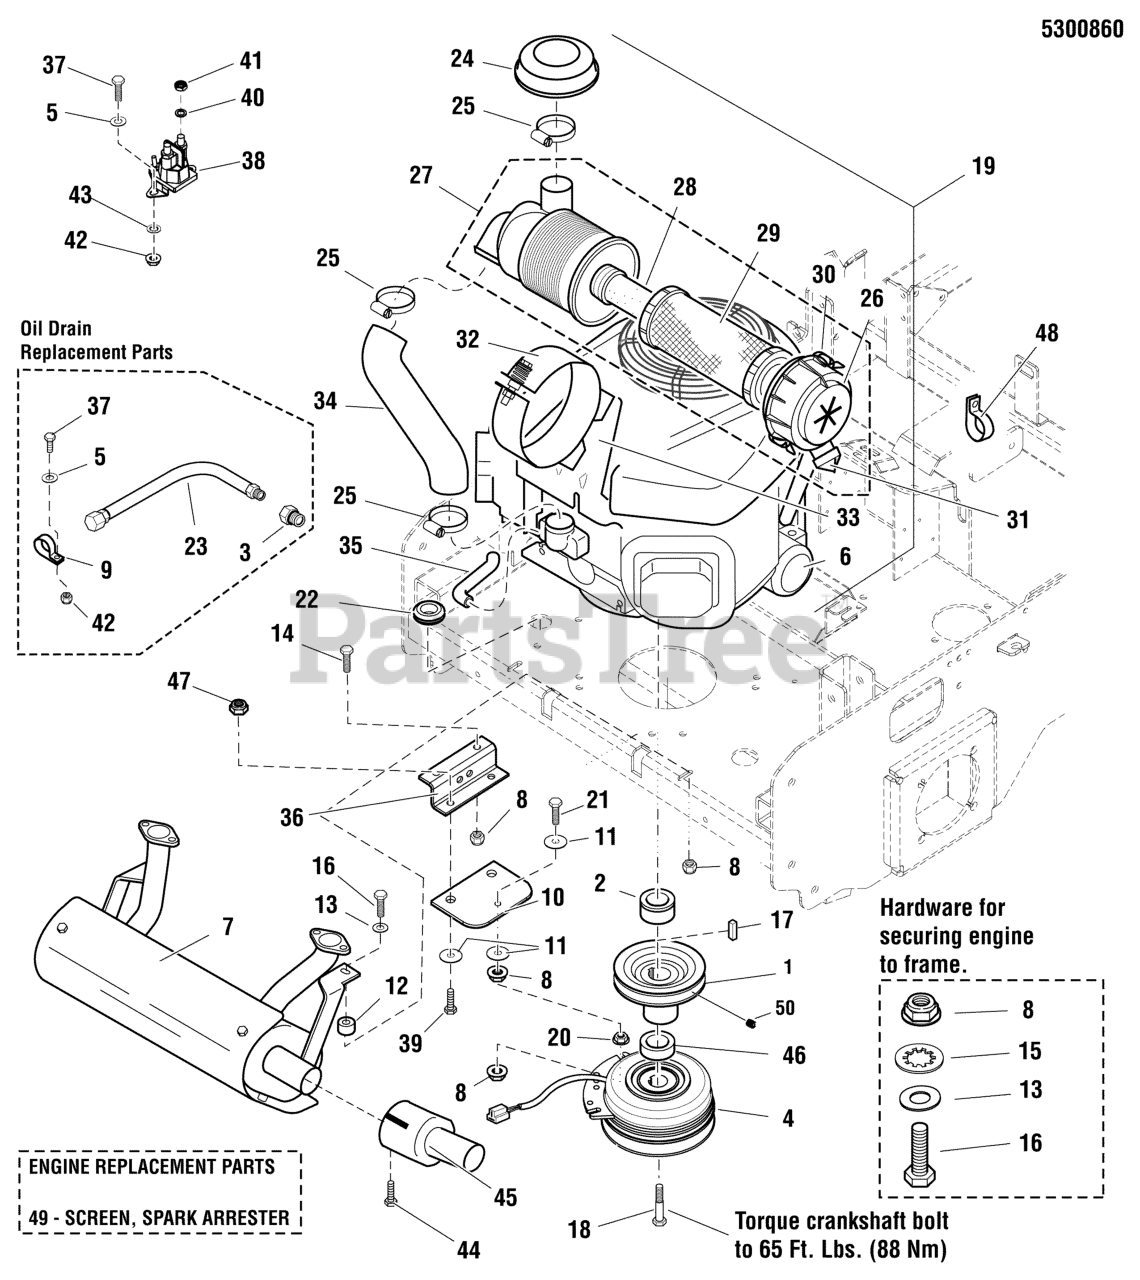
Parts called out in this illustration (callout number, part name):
1	PULLEY, 5.15 OD X 1-1/8 BORE B-SECT
2	SPACER, 1.13 X 1.75 X 1.03, CZ
3	ADAPTER, Oil Drain
4	CLUTCH WARNER 200 FT-LB 1.13 X 6.323
5	WASHER, 1/4 SAE
6	FILTER,OIL,KAWA FX751,801,851,921,100
7	MUFFLER, 21HP-25HP KAWASAKI ENGINES
8	NUT, 5/16-18 HEX NYLOCK FLANGE NUT
9	CLAMP, VINYL INSULATED, 1.00
10	CLUTCH ANCHOR PAD
11	WASHER, .34 X 1.25 X 10 GA
12	SPACER, .39 X 1.00 X .80, CZ
13	WASHER, 5/16" SAE
14	BOLT, 5/16-18 X 1" GRD5 YZ
15	WASHER, 5/16" Internal Tooth Lock
16	BOLT, 5/16-18 X 1-3/4" GD5 YZ
17	KEY, 1/4 SQ X 1
18	BOLT, CRANKSHAFT, 7/16" X 2-1/2"
20	NUT, 5/16-18 HEX SERRATED FLANGE (LARGE)
21	BOLT, 5/16-18 X 2-1/4 TFL, GD5 YZ
22	GROMMET, 7/8"
23	HOSE, OIL DRAIN
24	RAIN CAP, AIR FILTER, 22,24&26HP, KAWASAKI (SV)
25	CLAMP, HOSE
26	CAP END, FILTER CASE
27	AIR FILTER ASSEMBLY, Complete
28	AIR FILTER, ELEMENT, SECONDARY
29	AIR FILTER, ELEMENT, PRIMARY
30	CLAMP, Cap
31	RUBBER, Dust Valve (SV)
32	CASE, BRACKET, COMPLETE
33	BRACKET PLATE
34	AIR INLET TUBE
35	BREATHER TUBE
36	ANCHOR, CLUTCH - BLK
37	BOLT, 1/4"-20 X 3/4" GD5 YZ
38	SOLENOID-4 POLE 12 VOLT DC (TROMBETTA)
39	BOLT, 3/8-16 X 1" GD5 CZ
40	WASHER, Light Lock, 5/16
41	NUT, Hex Jam, 5/16-24
42	NUT, 1/4-20 Hex Nylock Flange
43	WASHER, 1/4 INTERNAL TOOTH LOCK
44	SCREW, SELF-TAP, #8-32 X 3/8. WASH HEX, CZ
45	EXTENSION, TAILPIPE, 3" - BLACK
46	SPACER, 1.13 x 1.75 x .62
47	NUT, 3/8 - 16 HEX NYLOCK FLANGE
48	CLAMP, VINYL INSULATED, 1.00
50	SET SCREW, 5/16-18 X 3/8, KNURL, W/PATCH
